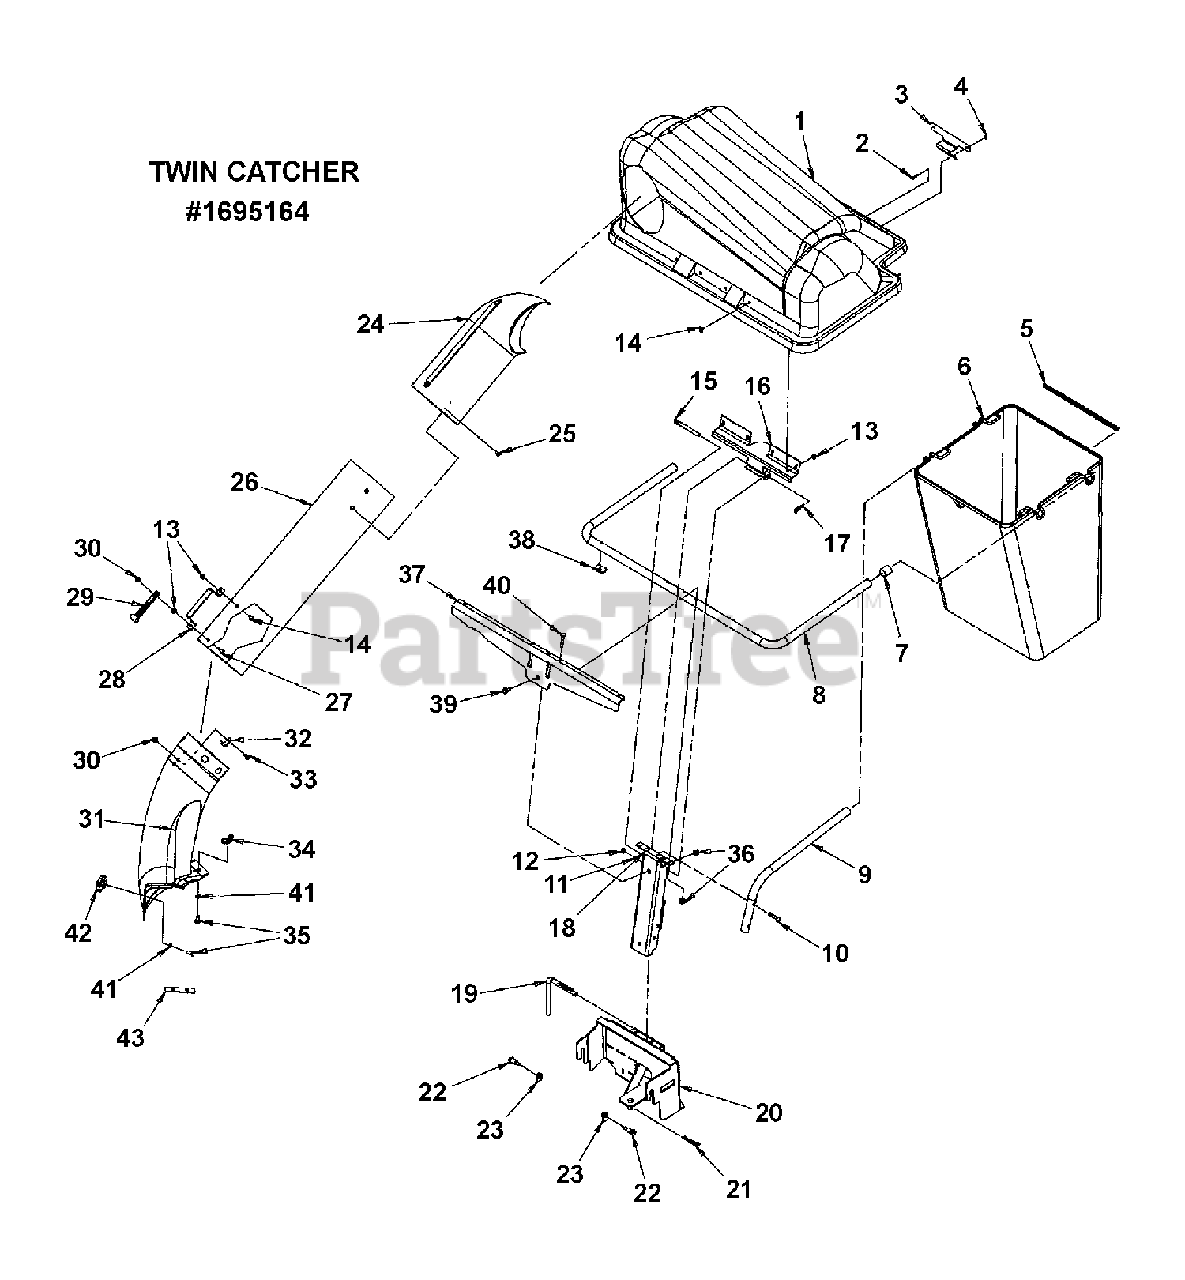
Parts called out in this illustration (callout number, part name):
1	COVER, ASSY - TWIN W/DECAL
2	SCREW, 10-24 X .75
3	LATCH
4	NUT, #10-24 ESNA LOCK
5	EDGING, 13.12 LONG PVC
6	BAG, ASSY - TWIN
7	CAP, (24862)
8	TUBE, U, 5-HOLE
9	TUBE, CENTER (54412)
10	SCREW, .312-24 CURVE (6x93)
11	LOCKWASHER, .312 SPRING
12	NUT, .312-24 HEX
13	NUT, .25-20 KEPS LOCK
14	SCREW, .25-20 x .5 SLOT 4x24
15	PIN, COVER HINGE (54407)
16	HINGE, COVER (54398)
17	PIN, HAIR .090
18	CHANNEL, ASSY
19	PIN, CHANNEL MOUNT
20	MOUNT, ASSY - CHANNEL
21	PIN, HAIR .125 x 2.56 LG
22	BOLT, SHOULDER .312-18
23	NUT, .312-18 SPEED
24	ELBOW, UPPER TUBE
25	SCREW, .25 x .75 PHLP 26x239
26	TUBE, CLEAR
27	SCREW, .25-20 x 1.0 (4x71)
28	HANDLE, TUBE (54416)
29	STRAP, RUBBER
30	NUT, .25-20 C TRLK FLG
31	BOOT, 38"/42"
32	PIN, LATCH (54563)
33	BOLT, CARRIAGE 25-20 x .62
34	NUT, .312-18 WING (14x86)
35	BOLT, CARRIAGE .312-18 x .75
36	NUT, 5/16-18 ESNA
37	BRACE, STIFFENER
38	CLAMP, SADDLE
39	CAP, SCREW 5/16-18 x .75 LG
40	BOLT, CARRIAGE .31-18 x 1.75
41	NUT, PUSH .312
42	KNOB, .312-18 INT 5-LOBE
43	SHIM, MOWER DEFL BRACKET
44	MANUAL, INSTRUCTION
